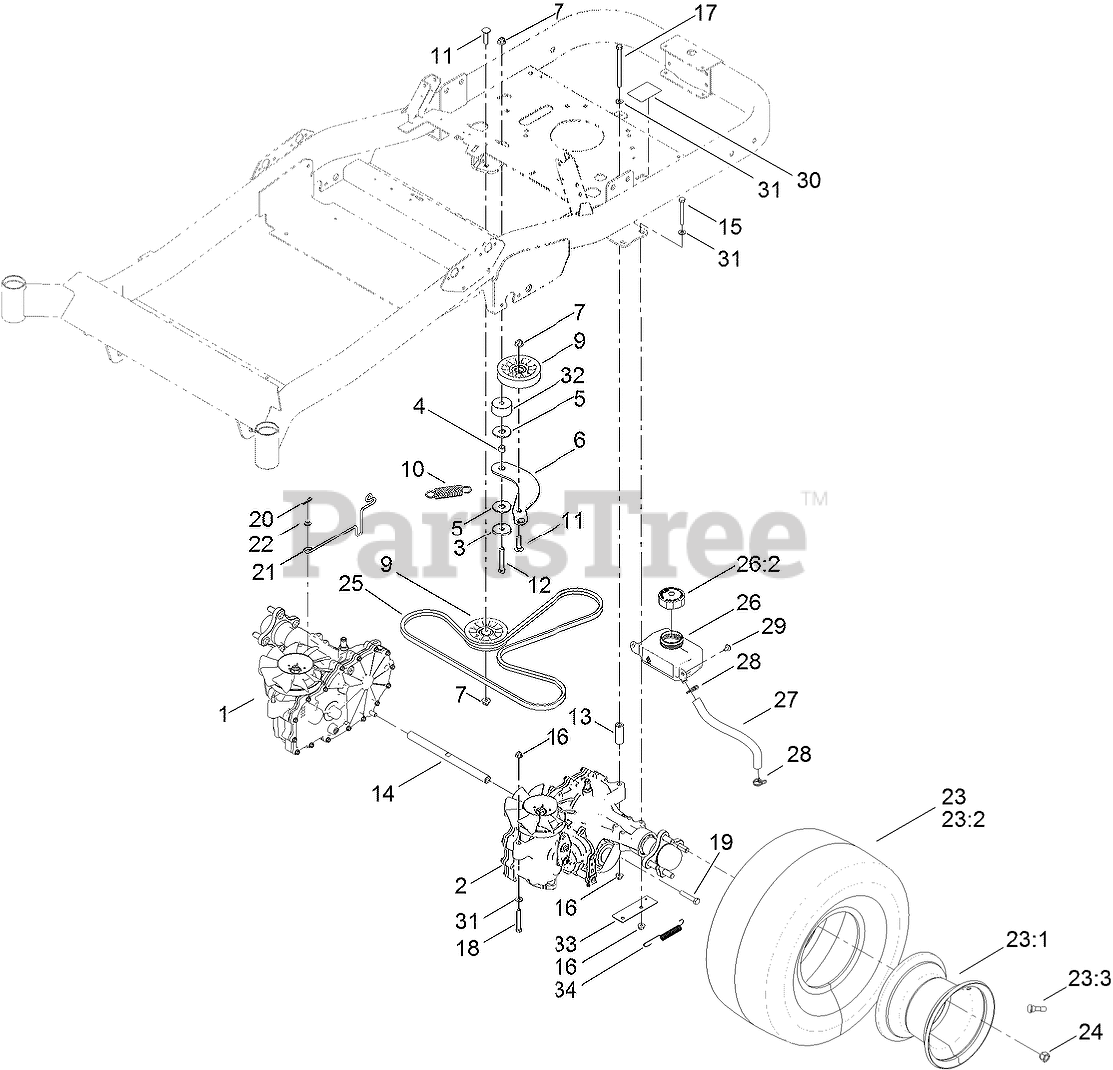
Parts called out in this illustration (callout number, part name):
1	RH HYDRO TRANSMISSION ASM
2	LH HYDRO TRANSMISSION ASM
3	WASHER-PLAIN
4	SPACER
5	WASHER-FRICTION, COMPOSITE
6	ARM-IDLER
7	NUT-HF, NI
9	PULLEY-IDLER, FLAT
10	SPRING-EXTENSION
11	SCREW-CARR
12	SCREW-HH
13	SPACER-HYDRO
14	SHAFT-CROSS, HYDRO
15	SCREW-HH
16	NUT-HF, NI
17	SCREW-HH
18	SCREW-HH
19	SCREW-HH
20	PIN-COTTER
21	ROD-BYPASS
22	WASHER-FLAT
23	4 PLY WHEEL AND TIRE ASM
23:2	TIRE-4 PLY
23:3	STEM-VALVE
23:4	TUBE-INNER
24	NUT-LUG
25	V-BELT
26	HYD RESERVIOR ASM
26:2	CAP-RESERVOIR, HYD
27	HOSE-OVERFLOW
28	CLAMP-HOSE
29	SCREW-HHFTF
30	DECAL-BYPASS
31	WASHER-PLAIN
32	SPACER
33	PLATE-SPRING
34	SPRING-EXTENSION
